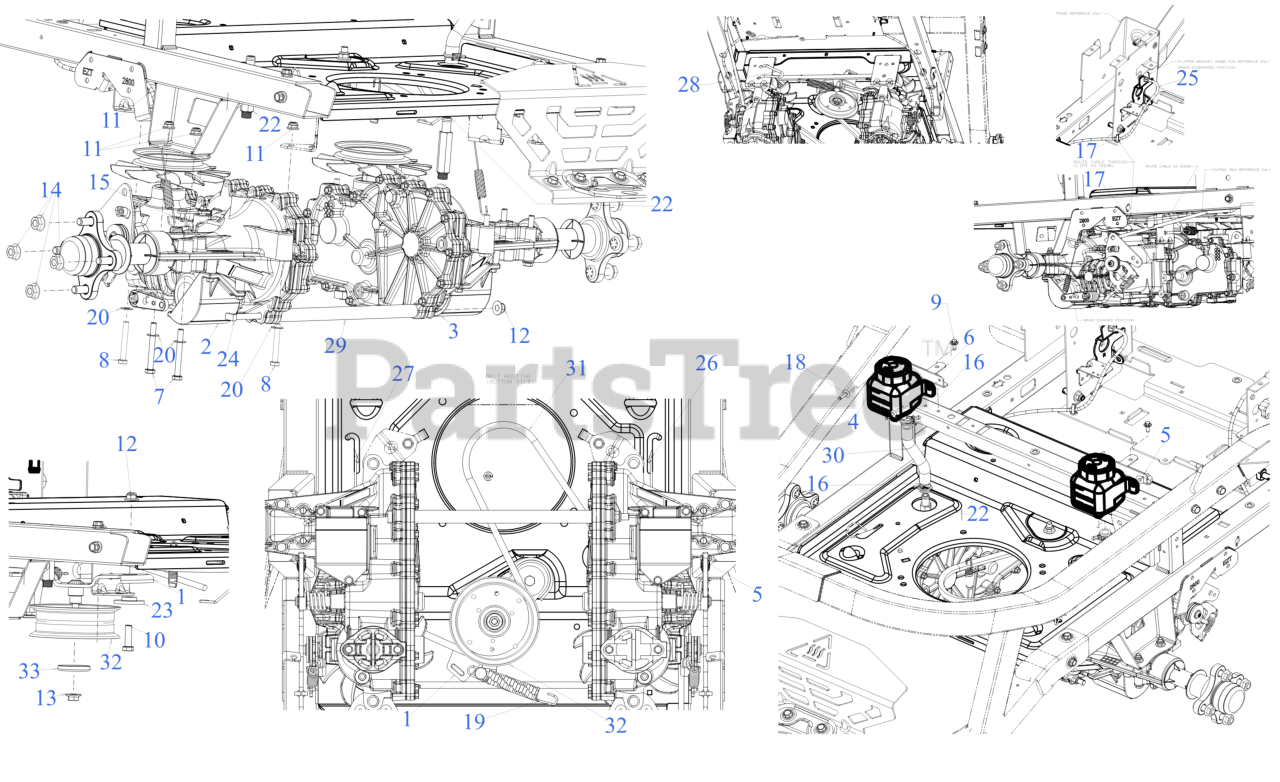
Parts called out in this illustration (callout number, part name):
1	DRIVE IDLER BRACKET
2	HYDRO TRANSMISSION (LH)
3	HYDRO TRANSMISSION (RH)
4	EXPANSION TANK
5	EXPANSION TANK BRACKET (RH)
6	EXPANSION TANK BRACKET (LH)
7	HEX SCREW 5/16-18 x 2.75
8	HEX SCREW 5/16-18 x 2.25 GR5
9	SCREW M6-1 x .625
10	SCREW 3/8-16 x 1.25 GR5
11	FLANGE LOCK NUT 5/16-18
13	FLANGE LOCK NUT
14	HEX FLANGE NUT 7/16-14
15	BOW TIE COTTER PIN 1/4-5/16
16	FUEL HOSE CLAMP .75
17	CABLE RETAINER CLIP
18	POP RIVET - .188 DIAMETER
19	EXTENSION SPRING .81 x 5.37
20	FLAT WASHER
22	EXTENSION FITTING 9/16-18
23	SHOULDER SPACER
24	SUPPORT TUBE ROD
25	PARK BRAKE CABLE
26	HYDRO BYPASS ROD (RH)
27	HYDRO BYPASS ROD (LH)
28	IDLER SPRING HOOK
29	SUPPORT TUBE
30	EXPANSION TANK HOSE
31	TRANSMISSION DRIVE BELT A x 67
31	Cub Cadet TRANS DRIVE BELT A x 67 RZT
31	Troy-Bilt TRANSMISSION DRIVE BELT
32	IDLER PULLEY 4.50" DIA
33	IDLER PULLEY CAP
